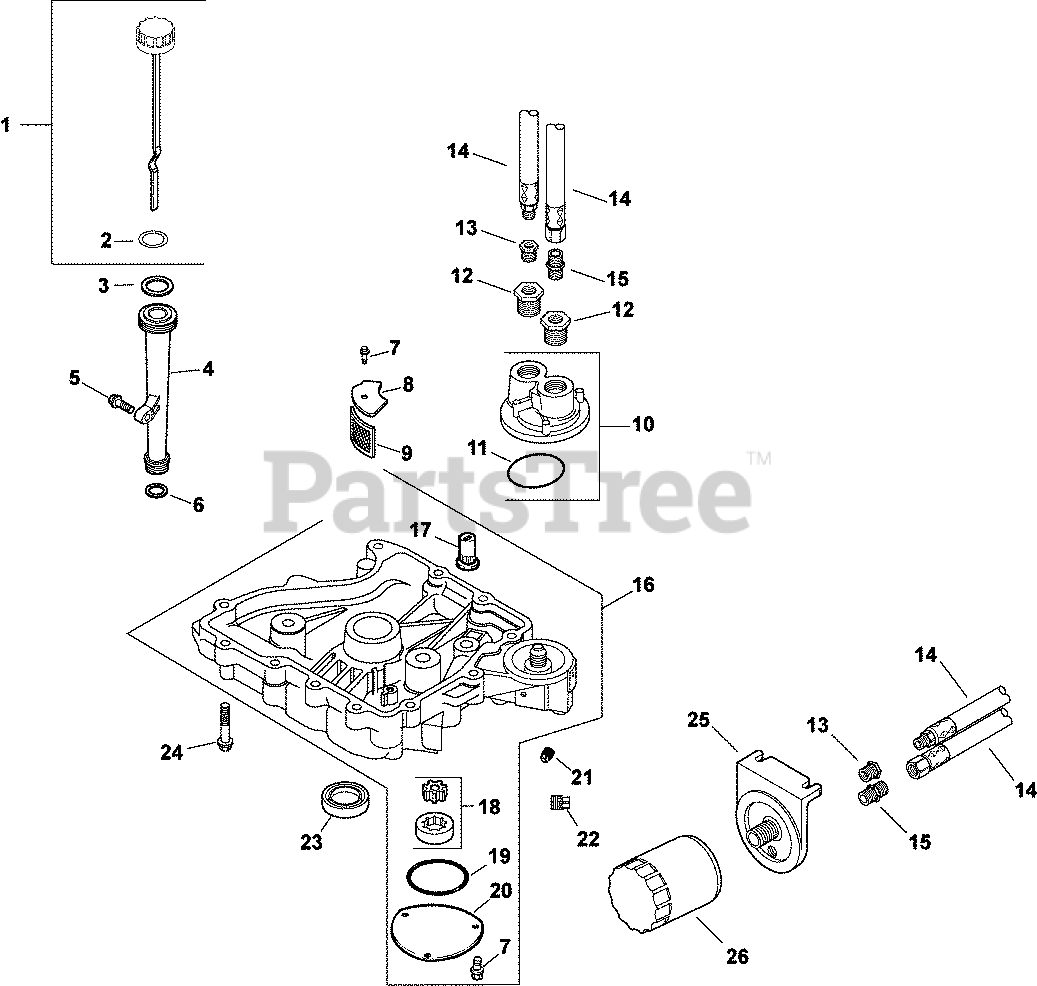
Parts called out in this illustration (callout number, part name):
1	DIPSTICK/CAP ASSY (YELLOW) - DISCONTINUED
2	O-RING, DIPSTICK
3	O-RING, UPPER OIL FILL TUBE
4	TUBE, OIL FILL USE 25 123 07-S
5	SCREW, FLG THD FRM M5X.8X20-(#25086399S)
6	O-RING, LOWER OIL FILL TUBE
7	SCREW,FLG THD FRM M5X0.8X16-(#25086398S)
9	SCREEN, OIL-USE 24 162 26-S
10	KIT,OIL FILTER ADAPTER
12	BUSHING, REDUCING
13	BUSHING, REDUCING
16	PAN, OIL
17	VALVE, OIL PRESSURE RELIEF
18	PUMP ASSEMBLY, OIL - DISCONTINUED
19	O-RING (2.5" DIA)
20	COVER, OIL PUMP
21	PLUG, PIPE 1/8 NPTF-SQ.HD.
22	PLUG, SQ HD PIPE 3/8"
23	SEAL, OIL
24	SCREW, FLG M8X1.25X45
26	OIL FILTER
